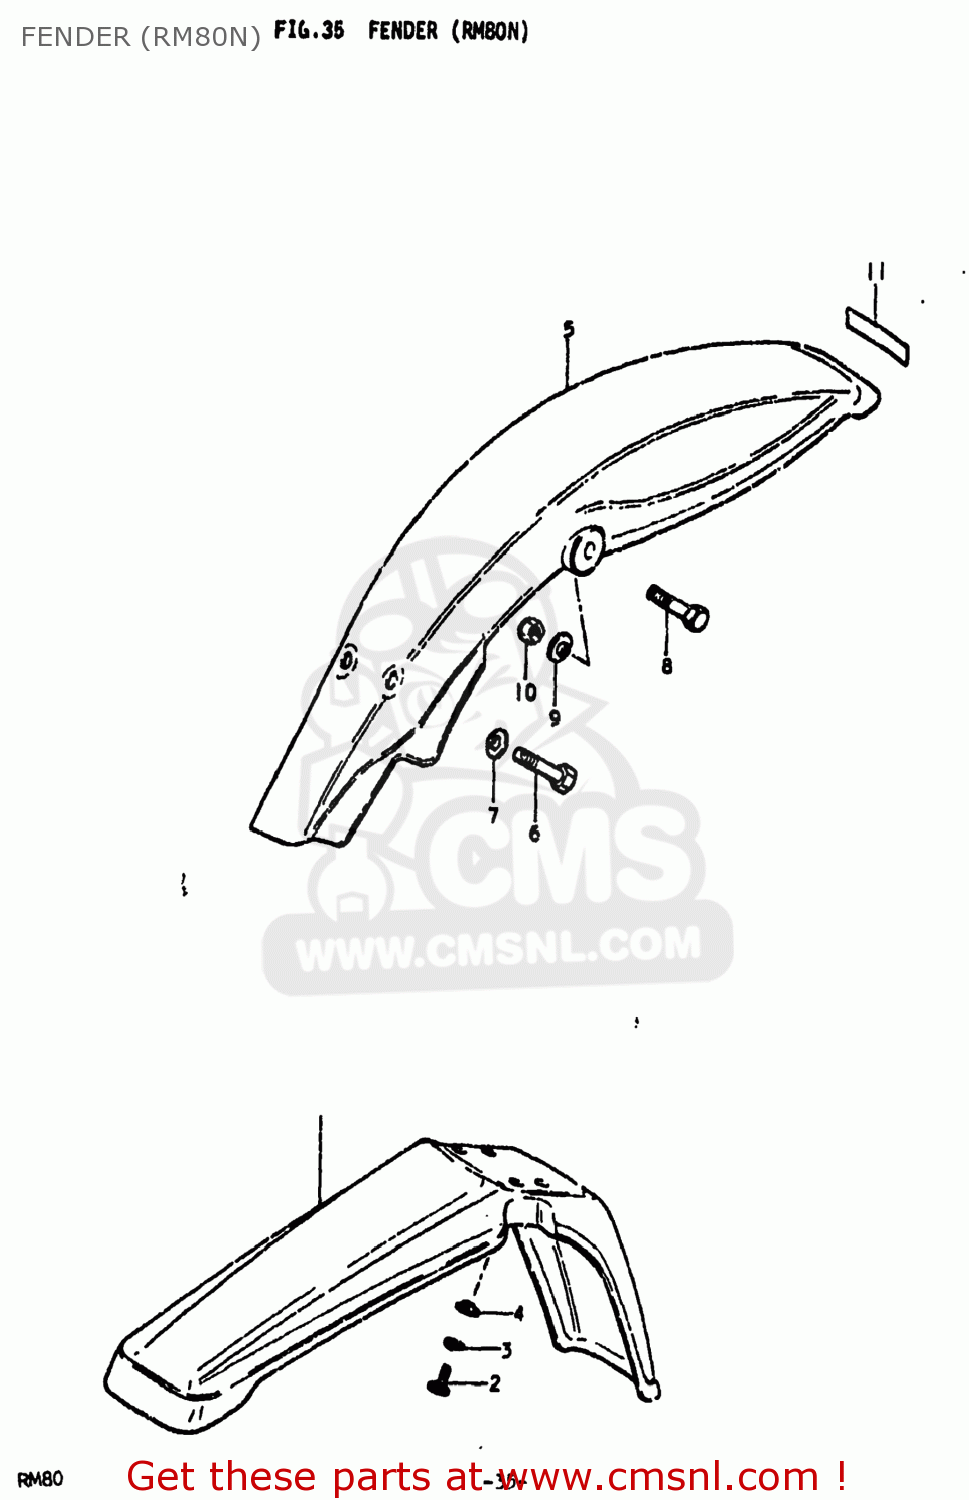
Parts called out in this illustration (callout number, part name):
1	FENDER,FRONT
2	BOLT, UPPER
3	LOCK WASHER
4	SPACER
5	FENDER,REAR
6	BOLT, UPPER
7	SPACER
8	BOLT
9	SPACER
10	NUT 6MM
11	EMBLEM,FRONT FENDER
